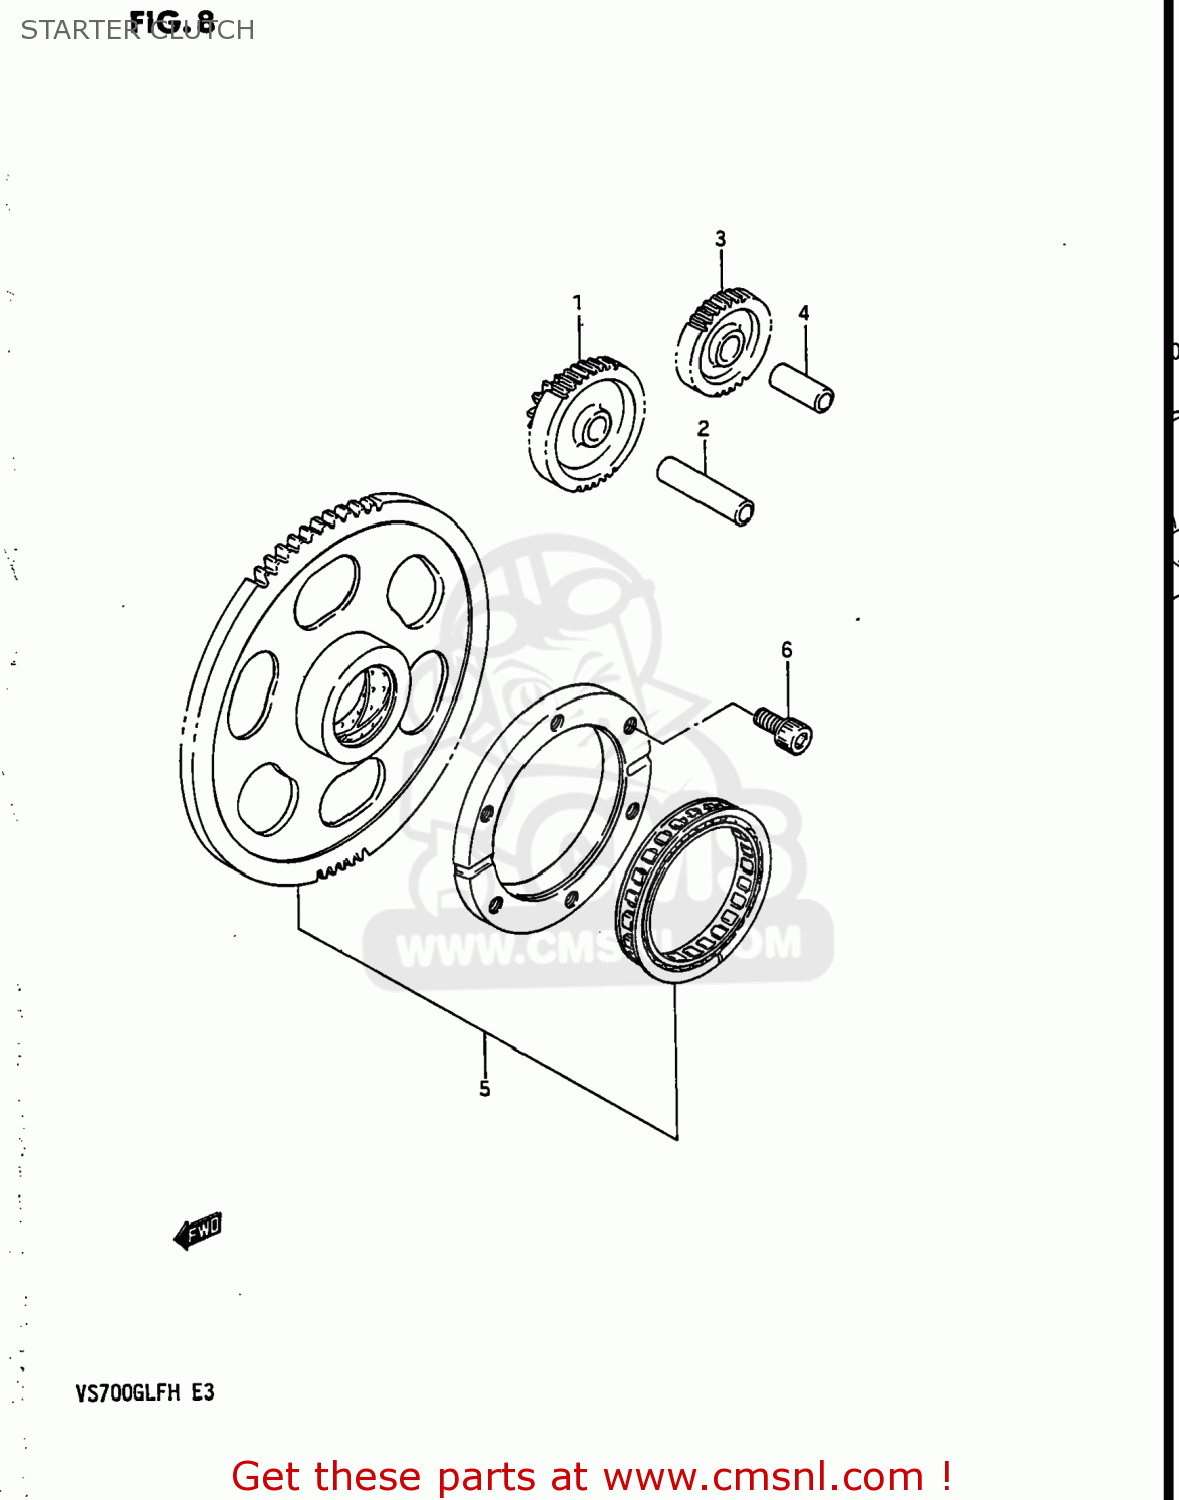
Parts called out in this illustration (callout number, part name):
1	GEAR,STARTER IDLE NO.1
2	PIN
3	GEAR,STARTER IDLE NO.2
4	PIN
5	CLUTCH SET,STARTER
6	BOLT
